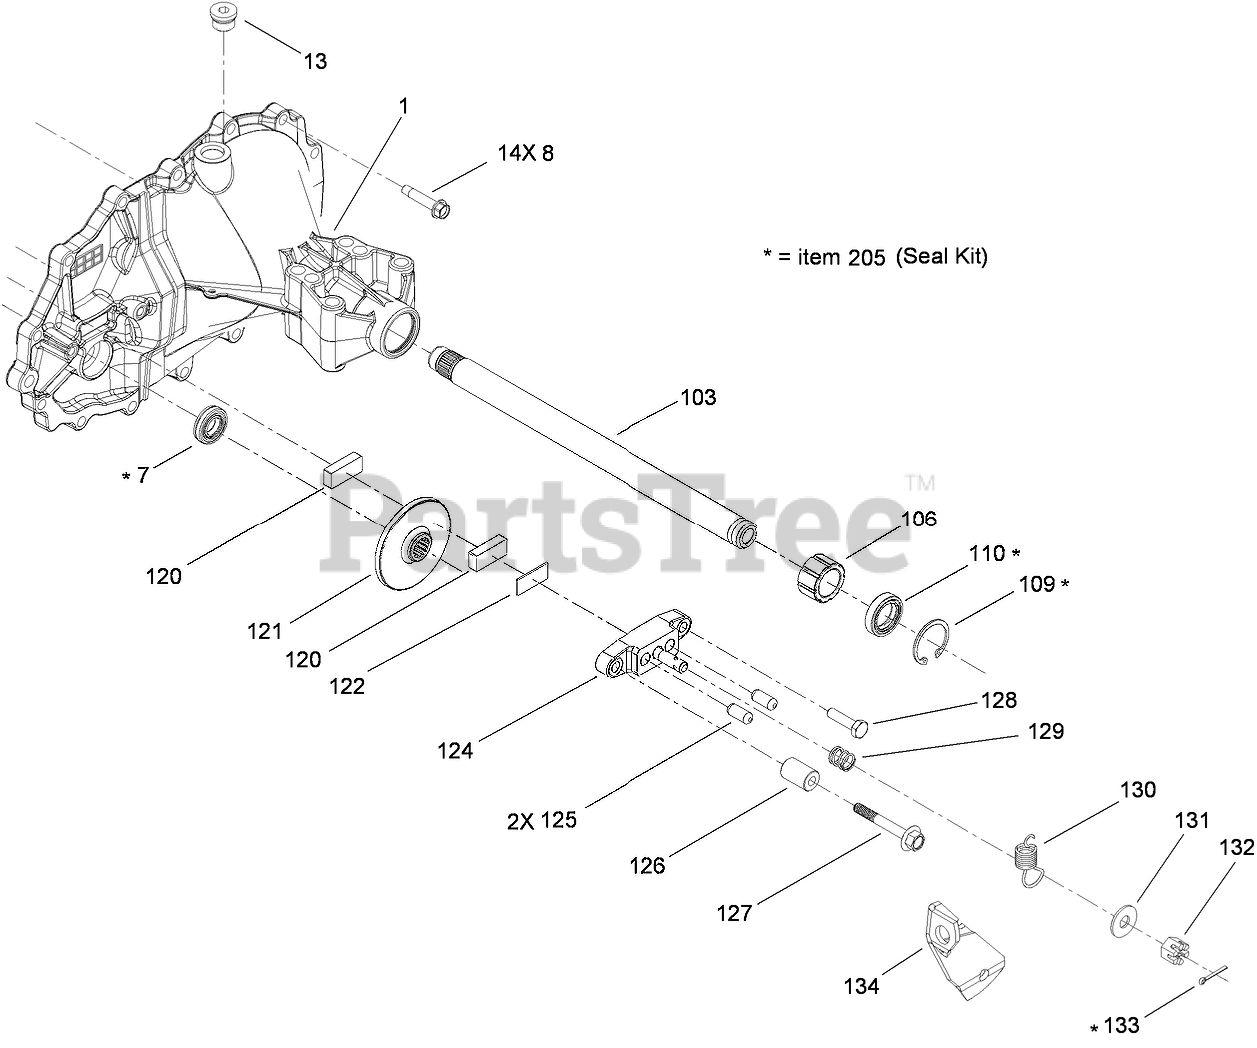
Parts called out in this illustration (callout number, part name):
1	MAIN HOUSING KIT
7	SEAL-LIP
8	SCREW-HHF
13	PLUG
103	SHAFT-AXLE, KEYED
106	BUSHING-OUTBOARD
109	RING-RETAINING, INTERNAL
110	SEAL
120	PUCK-BRAKE
121	ROTOR-BRAKE
122	PUCK-PLATE
124	YOKE-BRAKE
125	PIN-BRAKE
126	SPACER
127	SCREW-HF
128	SCREW-HHCS
129	SPRING-BRAKE, ANTI DRAG
130	ARM-BRAKE
131	WASHER
132	NUT-CASTLE
133	PIN-COTTER
134	SPRING-BRAKE, ARM
205	SEAL KIT
